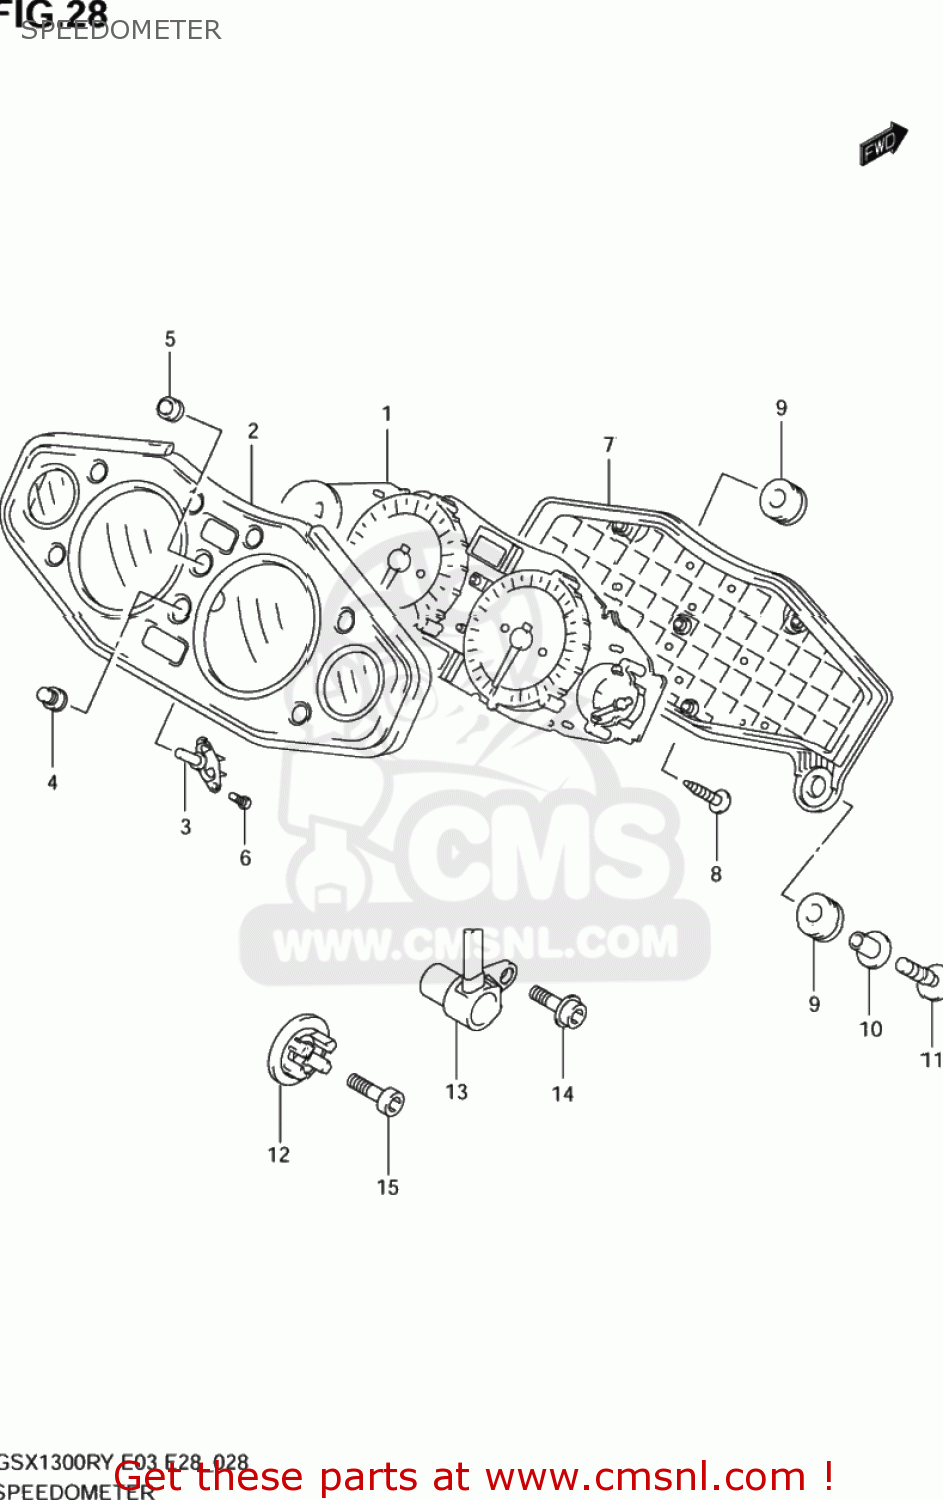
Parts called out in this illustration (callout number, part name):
1	SPEED & TACHOMETER ASSY
2	VISOR ASSY
3	ATTACHMENT,SWITCH
4	SWITCH,GUM
5	SWITCH,LEVER
6	SCREW(3X10)
7	CASE ASSY
8	SCREW
9	CUSHION
10	WASHER
11	BOLT(6X25)
12	ROTOR,SPEED
13	SENSOR,SPEED
14	BOLT
15	BOLT
